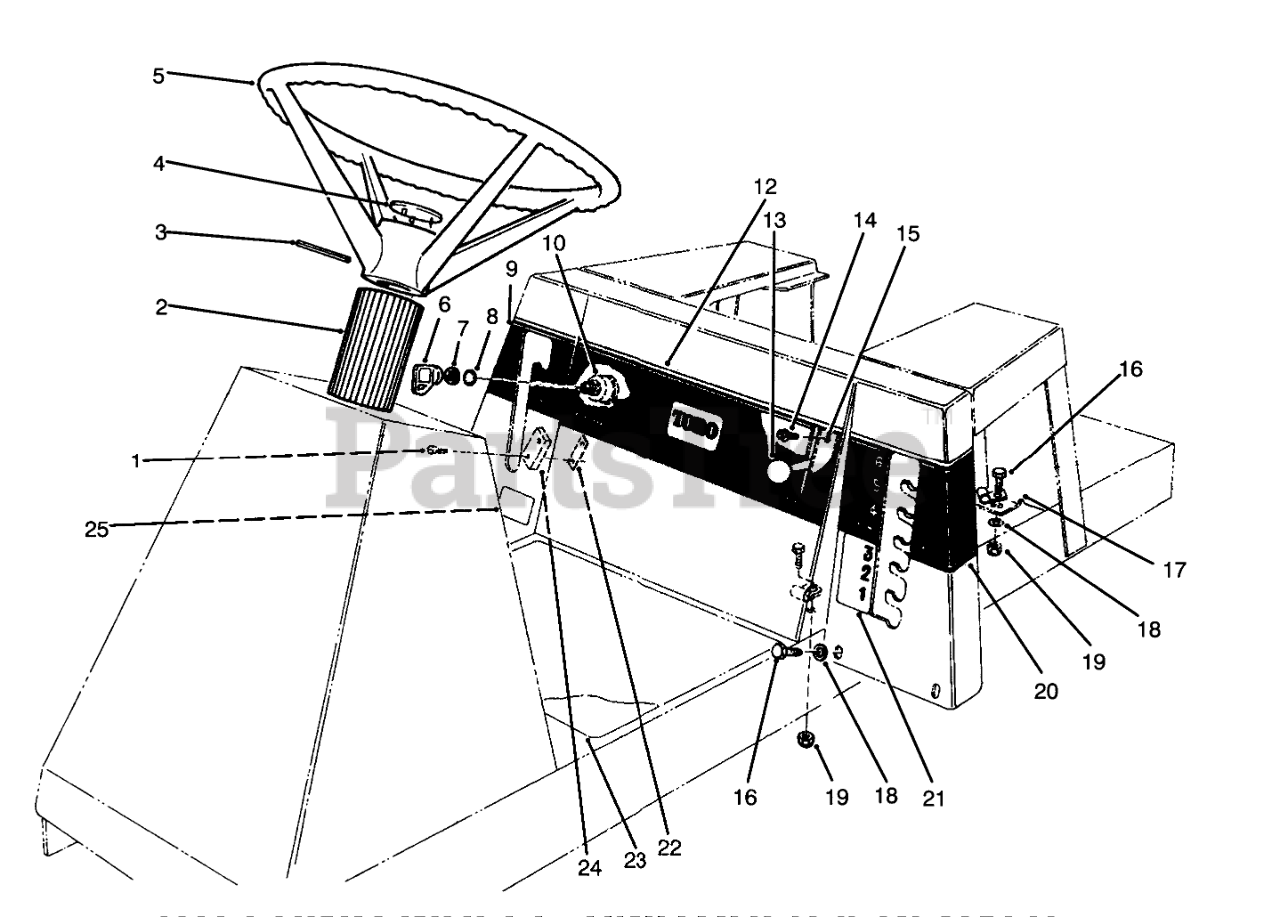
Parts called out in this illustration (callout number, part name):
1	SCREW-HH
2	COVER-STEERING SHAFT
3	PIN-ROLL
4	STEERING WHEEL INSERT
5	Assy.-Wheel, Steering (Incl. Ref. #4)
6	KEY-IGNITION
7	NUT-HH
8	WASHER-TOOTH, INTERNAL
9	DECAL-UPPER DECK ENGAGE
10	Switch-Ignition (Incl. Ref. #6-8) (Model No. 70042)
10	Switch-Ignition (Incl. Ref. #6-8) (Model No. 70080, 70120 & 70140)
11	DECAL - SHIFT PATTERN
12	DECAL-FRT SEAT CONTROLS
13	KNOB-CONTROL
14	SCREW-HWHTF
15	Control-Throttle (Incl. Ref. #13)
16	SCREW-HH
17	CLAMP
18	WASHER-PLAIN
19	NUT-LOCK, NI
20	DECAL - UPPER HOC
21	DECAL - LOWER HOC
22	NUT-SPEED
23	INSTRUCTION DECAL
24	SWITCH-MICRO
25	DECAL-LOWER DECK ENGAGE
